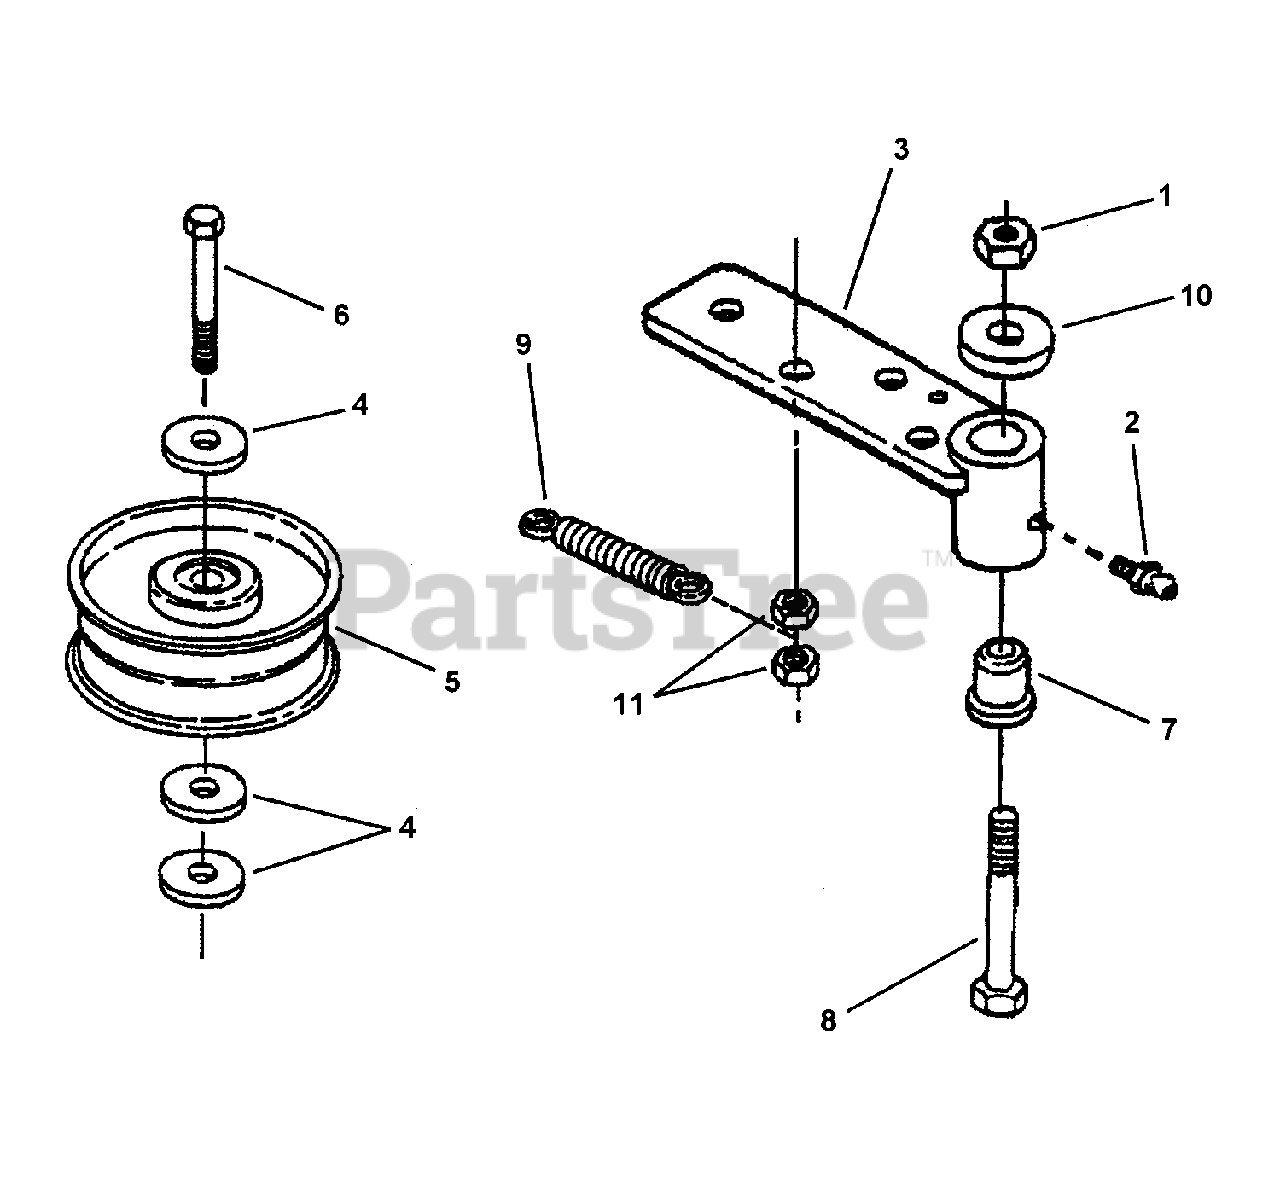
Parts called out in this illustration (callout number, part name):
1	NUT, 3/8-16, HEX TOP LOCK
2	GREASE FITTING, 1/4-28 Straight
3	IDLER ARM Weldment
4	WASHER, .44 x 1.0 x .08 Flat
5	PULLEY, Idler
6	BOLT, 3/8-16 x 3-1/4" Hex Head, GR 5
7	SPACER, Pivot
8	BOLT, 3/8-16 x 3-1/2" Hex Head, GR 5
9	SPRING, Idler Tension (extension)
10	BUSHING, 1" x 14 Ga Machine
11	NUT, 3/8-16 HEX NYLON LOCK
